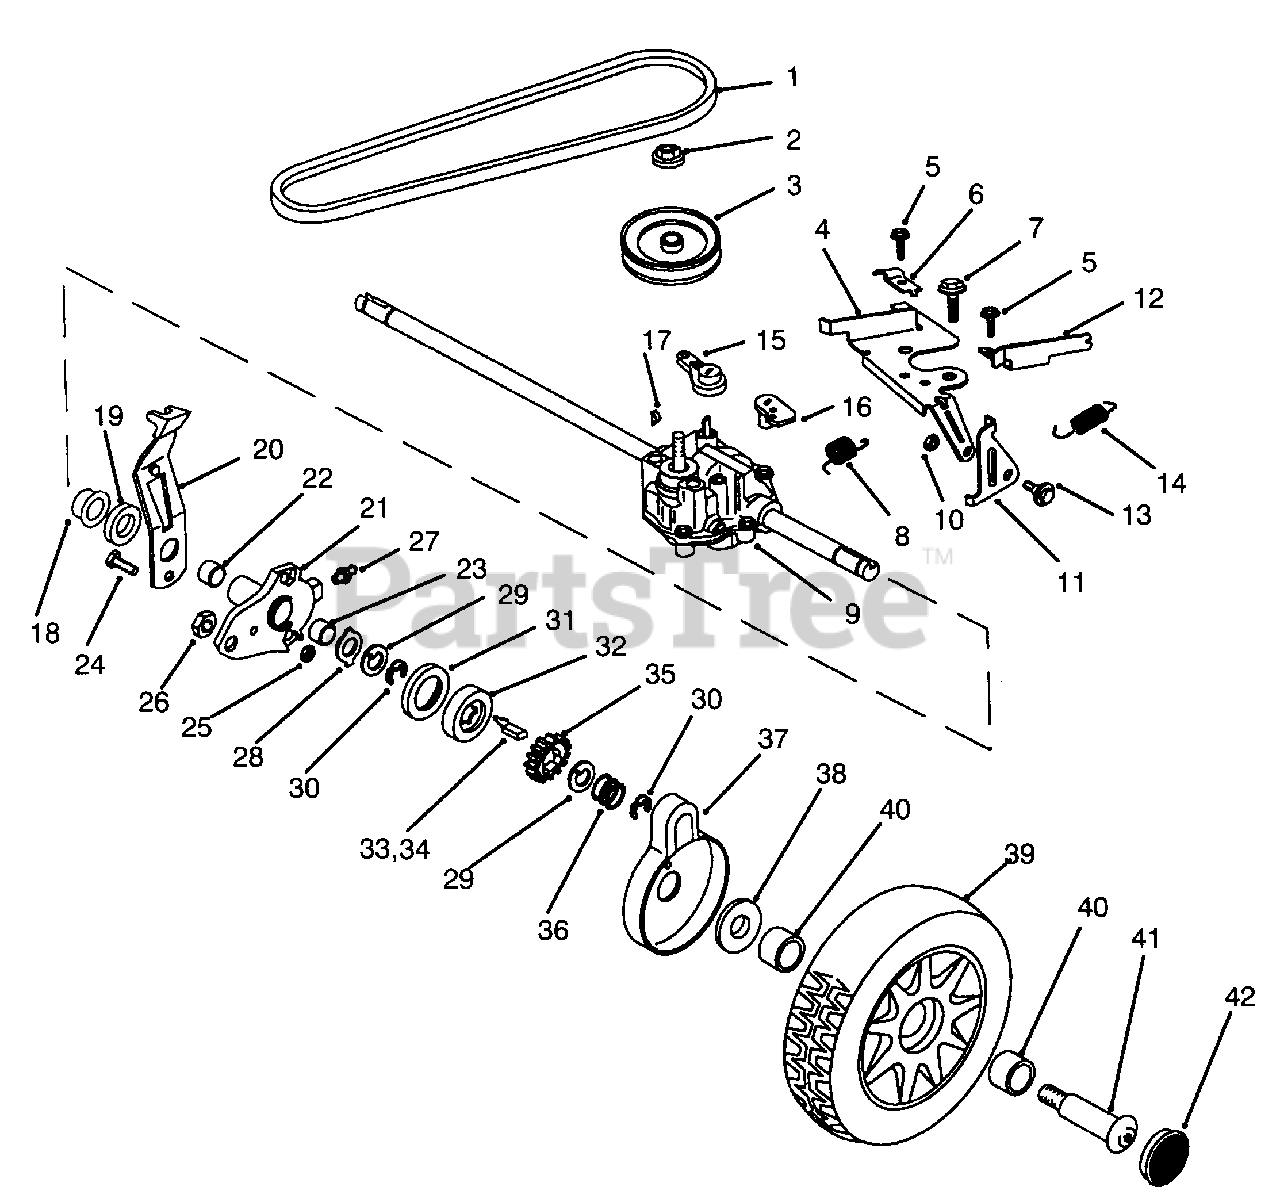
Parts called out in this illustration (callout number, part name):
2	Nut
3	Pulley-Transmission
4	Plate-Actuator
7	Screw-Plate to Trans.
9	Transmission
11	Arm-Trans. Engagement
12	Guide-Belt
13	Bolt-Shoulder
14	Spring-Extension
15	Arm-Shift
16	Arm-Clutch
18	Ring-Isolator
20	Assembly-Knob & Spring
21	Pivot Arm Assy. (Incl. Ref. No. 22-23)
22	Bushing
23	Bushing
25	Locknut
27	Fitting-Grease
28	Washer-Inner Thrust
29	Washer-Keyed
30	Ring-Retaining
31	Ring-Friction
32	Washer-Clutch
34	Key, Rocking-L.H.
35	Gear-Pinion 15T
36	Spring-Compression
37	Cover-Wheel
38	Washer-Stepped
39	Assembly-Wheel (Incl. Ref. No.40)
41	Bolt-Wheel
